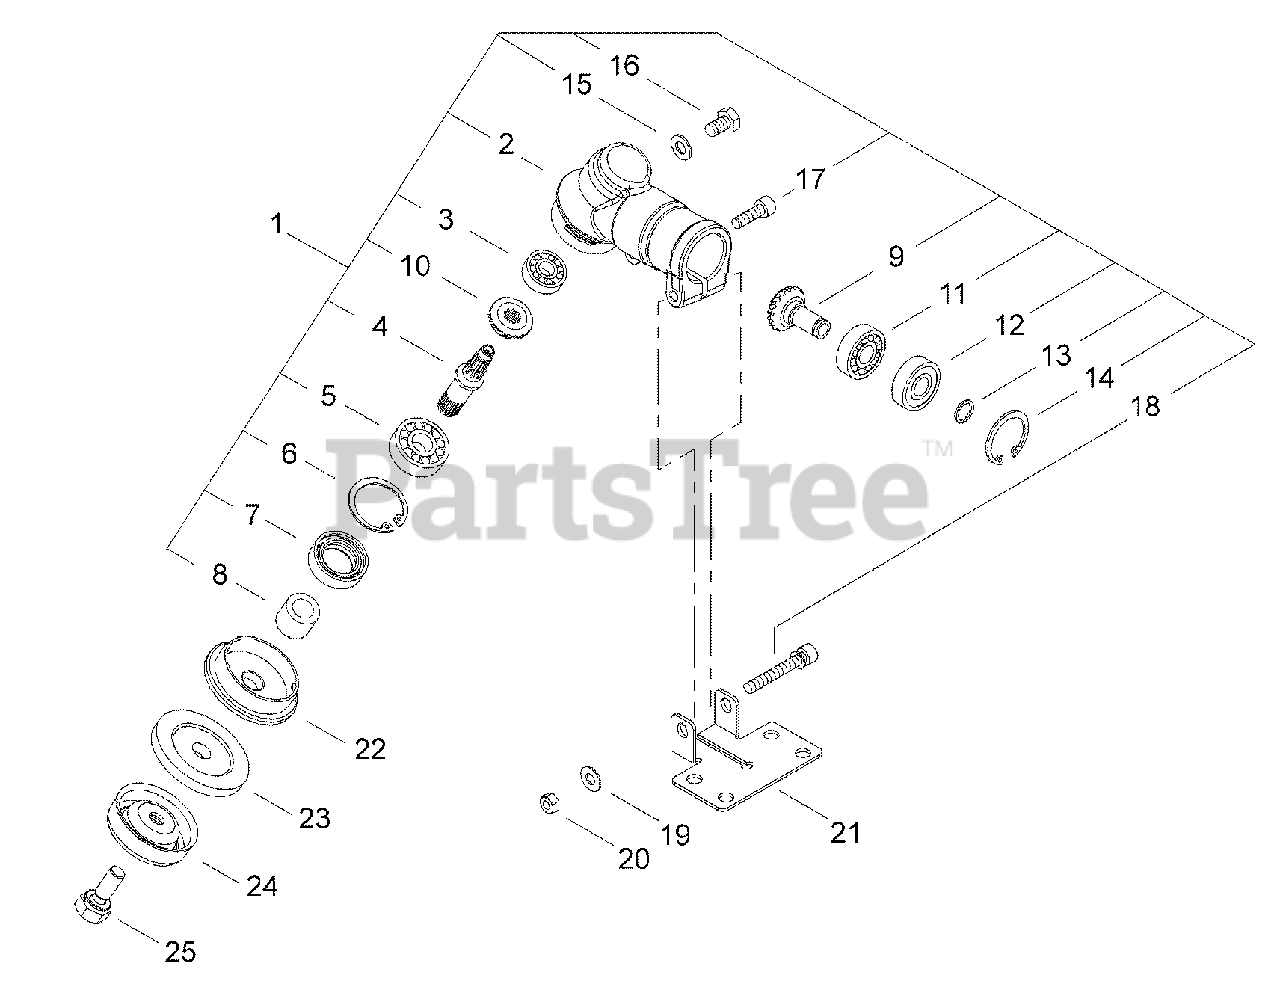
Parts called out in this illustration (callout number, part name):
1	GEAR CASE ASSY
2	HOUSING, GEAR CASE
3	BEARING, BALL 626 MOS
4	SHAFT, GEAR
5	BEARING, BALL 6000 MOS
6	RING, SNAP Ø26
7	SEAL, OIL
8	SPACER
9	GEAR, PINION
10	GEAR, BEVEL
11	BEARING, BALL 609 MOS
12	BEARING, BALL 609Z MOS
13	RING, SNAP Ø9
14	RING, SNAP Ø24
15	WASHER 6.5×11.5×0.8
16	BOLT M6×10
17	BOLT M5×10
18	BOLT M5×40
19	WASHER 5 MM
20	NUT M5
21	PLATE, SHIELD MOUNTING
22	PLATE, ADAPTOR - UPPER
23	PLATE, ADAPTOR - LOWER
24	GUARD, BOLT
25	BOLT M7×20
